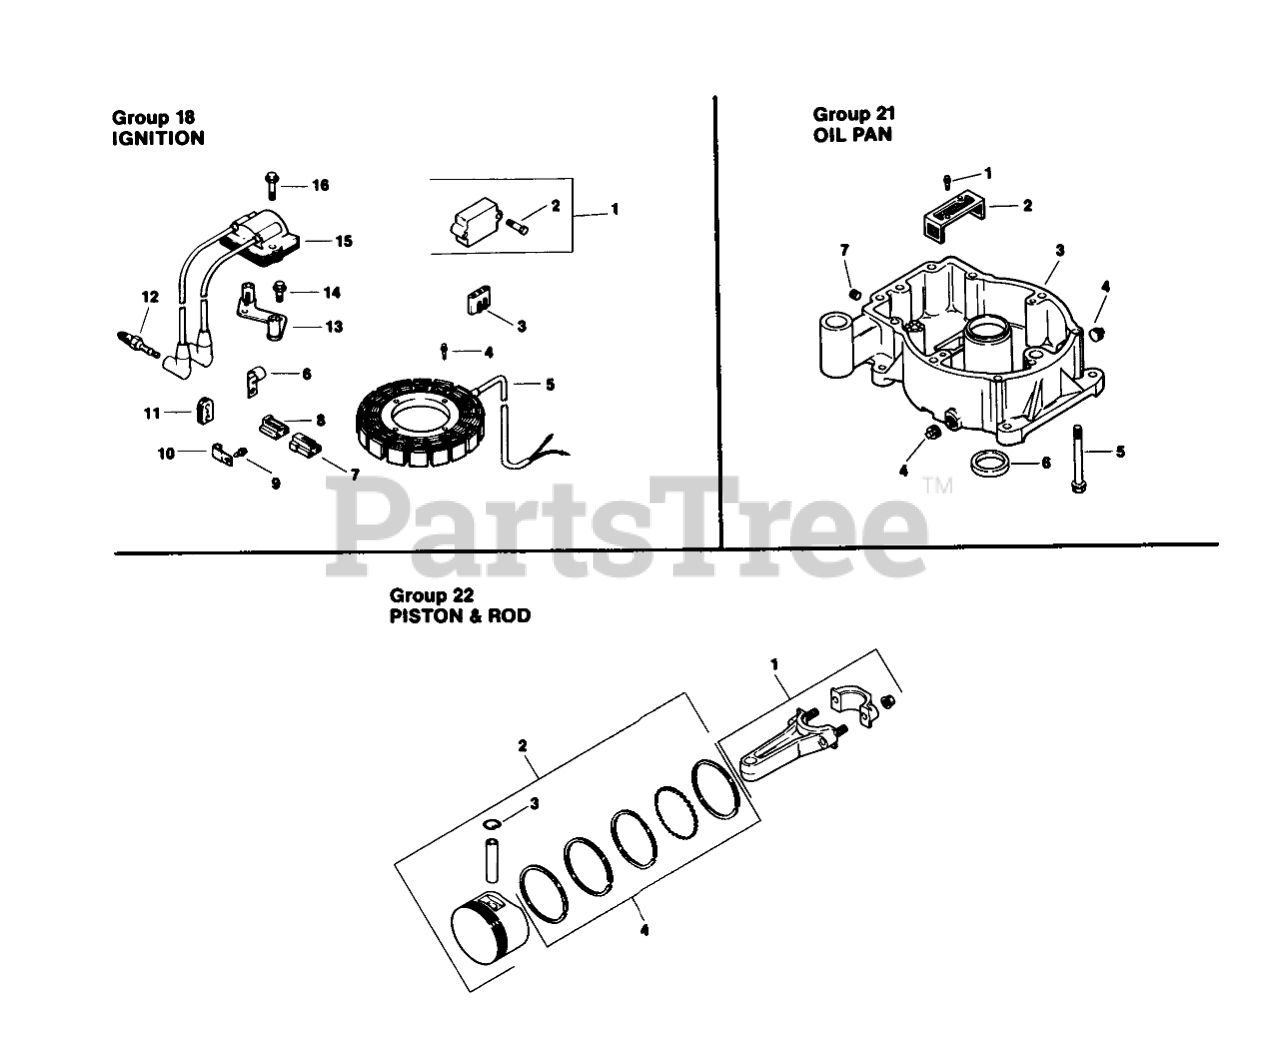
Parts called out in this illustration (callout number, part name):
1	Kit-Rectifier/Regulator (Incl. Ref. #2)
1	Screw
1	Rod-Connecting (Std.)
2	Screw
2	Filter-Oil Pickup
2	Piston w/Ring Set (Std.)
3	Connector
3	01 Pan-Oil
3	Retainer, Pin
4	Screw
4	Plug
4	Ring Set (Std. & .003)
5	Stator
5	Screw-Hex Washer Hd.
6	Clip
6	Seal-Rear Oil
7	Connector
7	Plug-Hex Countersunk
8	Connector
9	Screw
11	Grommet
12	Plug-Spark
13	Bracket-Module
14	Screw-Hex Washer Hd.
15	Module-Ignition
16	Screw-Hex Washer Hd.
20	Seal-Rear Oil
28	Screw-Hex Washer Hd.
